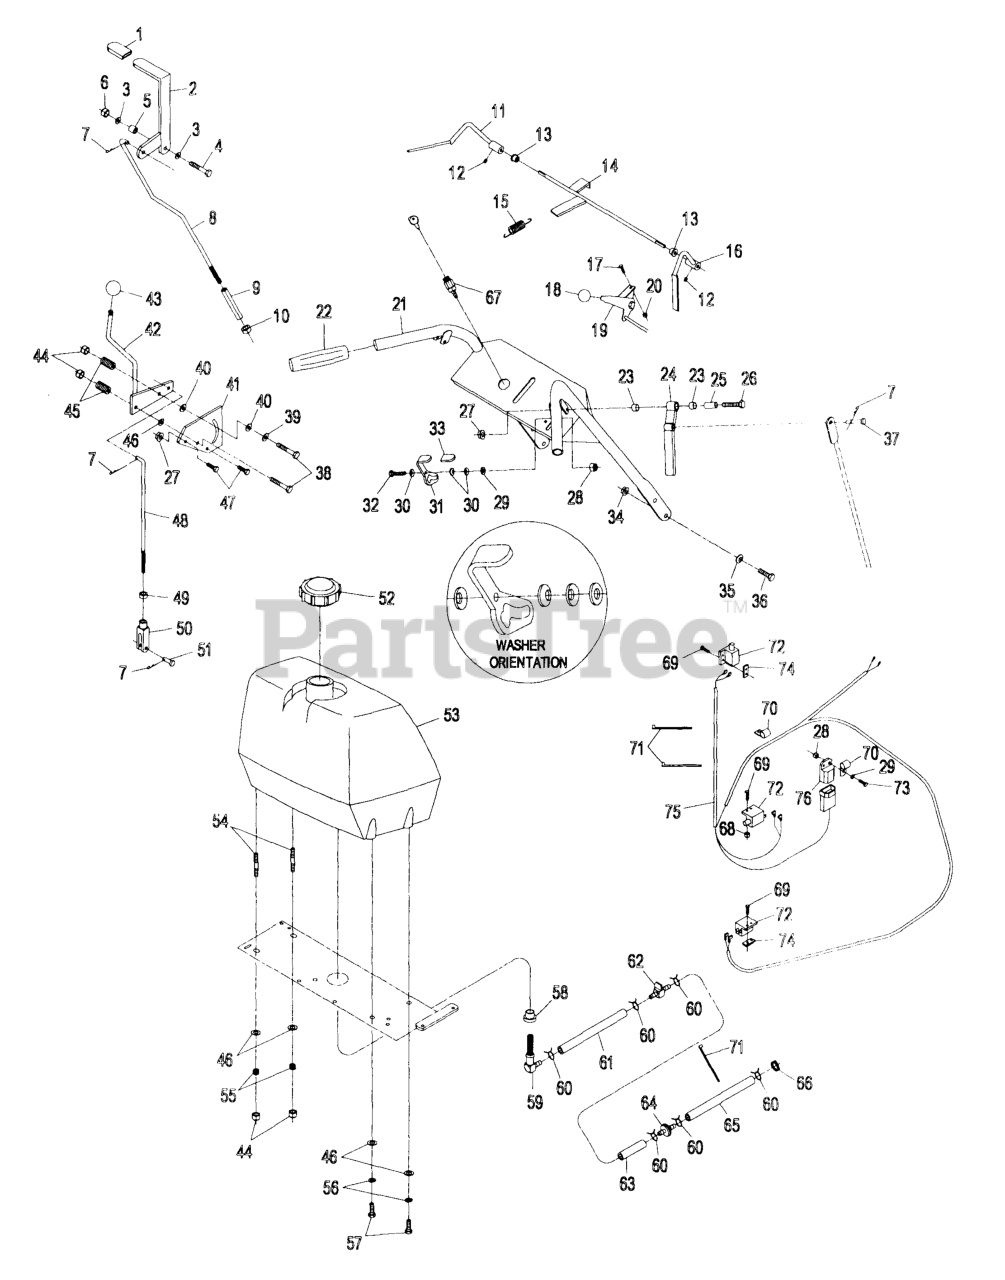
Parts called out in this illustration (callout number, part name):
1	GRIP-LEVER
5	BUSHING-LEVER, LIFT
7	PIN-COTTER
8	LINKAGE,UPPER
9	TURNBUCKLE
11	LEVER-LH
12	SCREW-SET
13	BUSHING-NYLON
14	WLD,ROD OPC
15	SPRING-EXTENSION
16	LEVER-RH
17	BOLT-CARR
18	KNOB-BALL
19	CABLE,THROTTLE CONTROL
23	BUSHING-SLEEVE
25	BUSHING-LEVER, DRIVE
30	WASHER-SPRING
33	GRIP-LATCH
37	PIN-CLEVIS
39	WASHER-FRICTION
40	WASHER-FRICTION
41	PLATE-LEVER, SHIFTER
43	KNOB-BALL
45	SPRING-COMPRESSION
48	ROD,SPEED CONTROL
50	YOKE-ADJUSTABLE
51	PIN-CLEVIS
52	CAP-FUEL
54	STUD
55	SPRING-TANK, FUEL
56	WASHER-LOCK
59	ELBOW-TANK, FUEL
60	CLAMP
61	HOSE-FUEL
62	VALVE-FUEL
63	HOSE-LINE, FUEL
65	LINE-FUEL
66	CLAMP-HOSE
67	SWITCH & KEY (INCLUDES NU
68	NUT-SQH
70	CLIP-LOOM
71	TIE-CABLE
72	SWITCH-OPEN, NORMALLY
74	PLATE-TAPPED
75	HARNESS,WIRING KAW TT
76	MODULE-INTERLOCK
